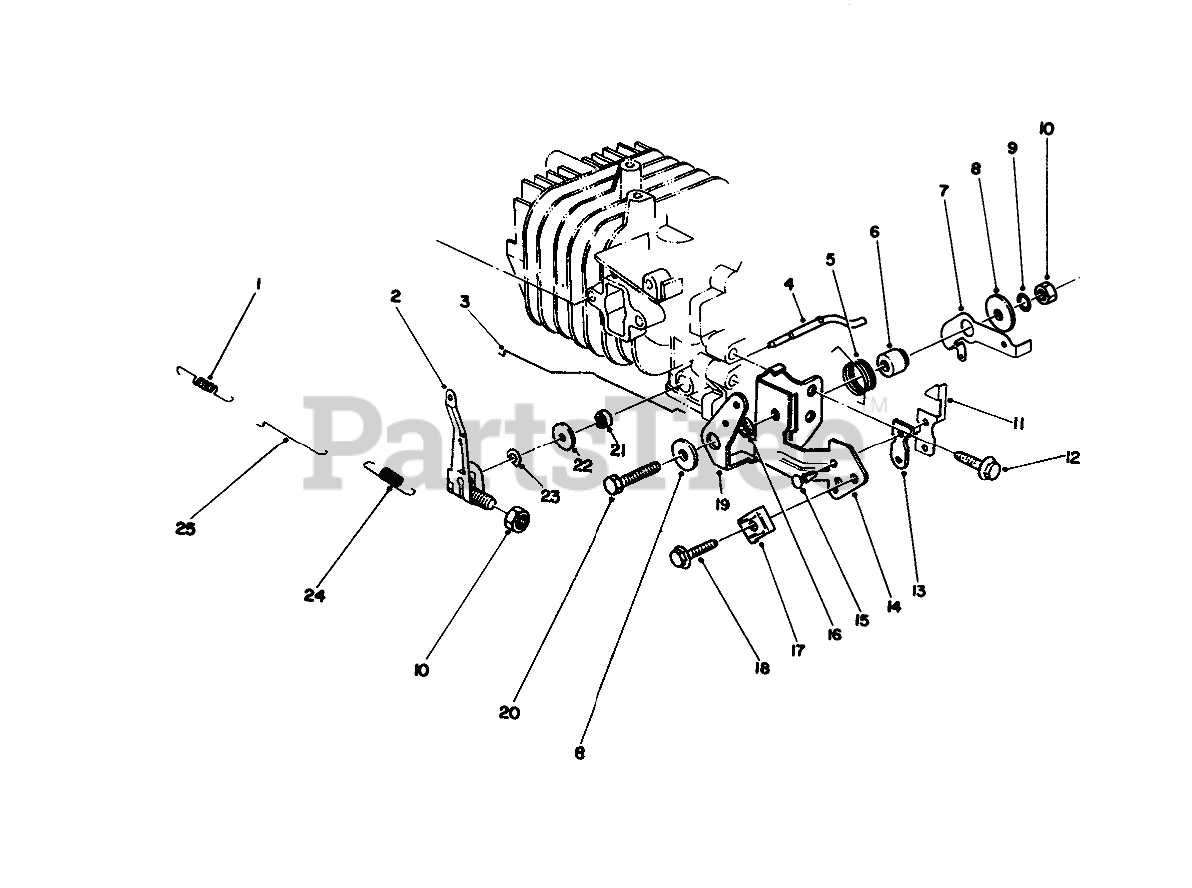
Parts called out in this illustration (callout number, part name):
1	SPRING
2	ARM-GOVERNOR
3	ROD-CHOKE
4	SHAFT
5	SPRING-CHOKE LEVER
6	Gov Lever Spacer
7	LEVER-SPRING, GOVERNOR
8	WASHER
9	LOCKWASHER
11	TERMINAL-KILL SWITCH
13	INSULATOR-KILL SWITCH
14	BRACKET-THROTTLE, CONTROL
15	KILL SWITCH RIVET
16	SPACER-CHOKE LEVER
17	CLAMP
19	LEVER-CONTROL, CHOKE
21	SEAL-OIL
22	WASHER
23	E-RING
24	SPRING-GOVERNOR
25	ROD-CARBURETOR
